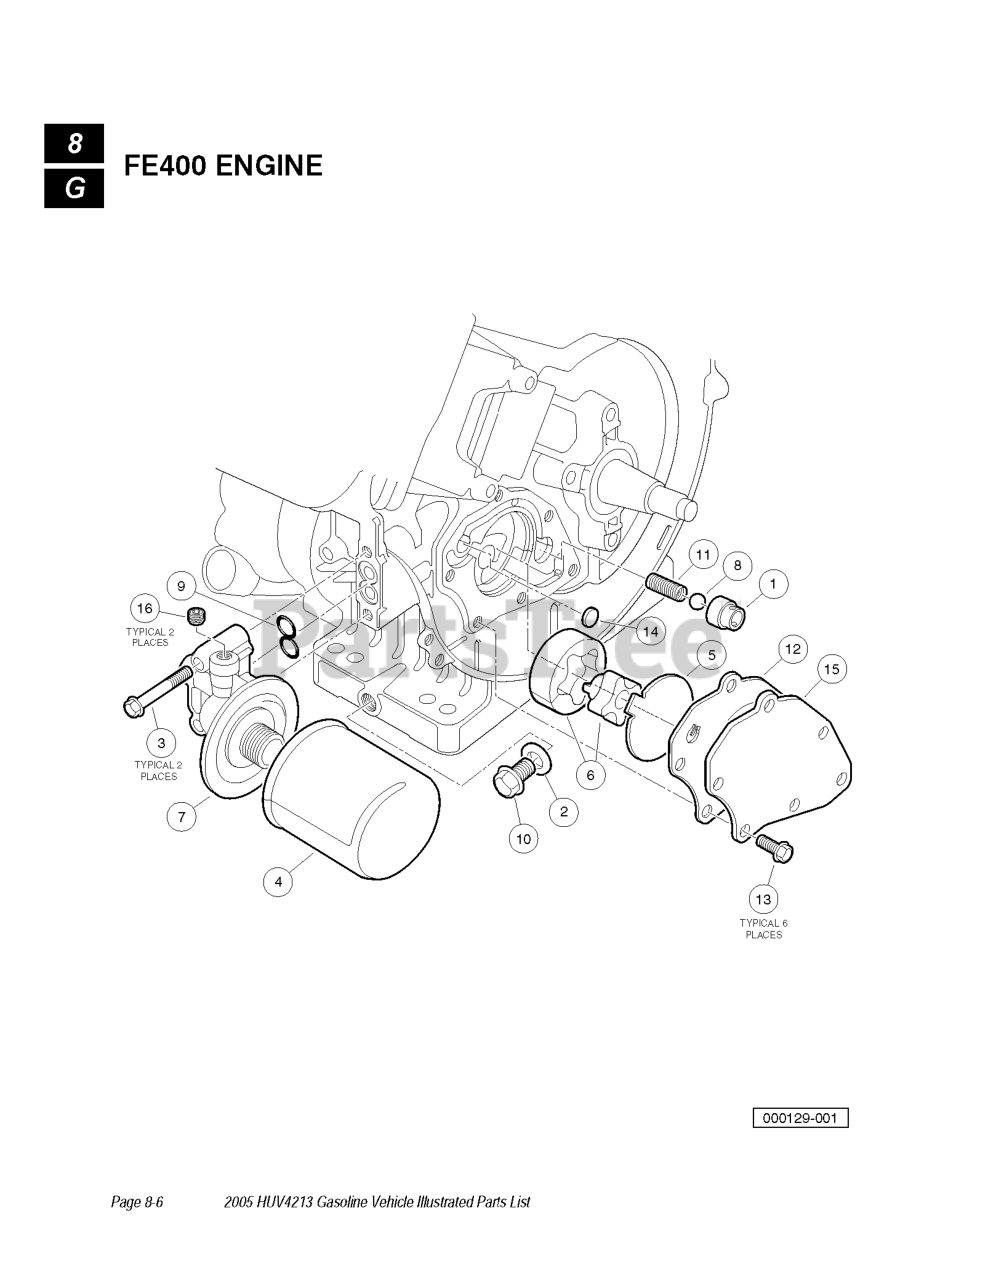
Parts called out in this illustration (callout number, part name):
1	SEAT, VALUE OIL PRESS RELIEF
2	GASKET, DRAIN PLUG
3	BOLT, FLANGED
4	FILTER, OIL
5	PLATE - OIL - PUMP
6	OIL PUMP AND ROTOR
7	BRACKET - OIL FILTER MOUNT
8	BALL, STEEL, PRESS, RELIEF
10	PLUG, DRAIN FE290D
13	BOLT - FLANGED SMALL
15	COVER - PUMP
